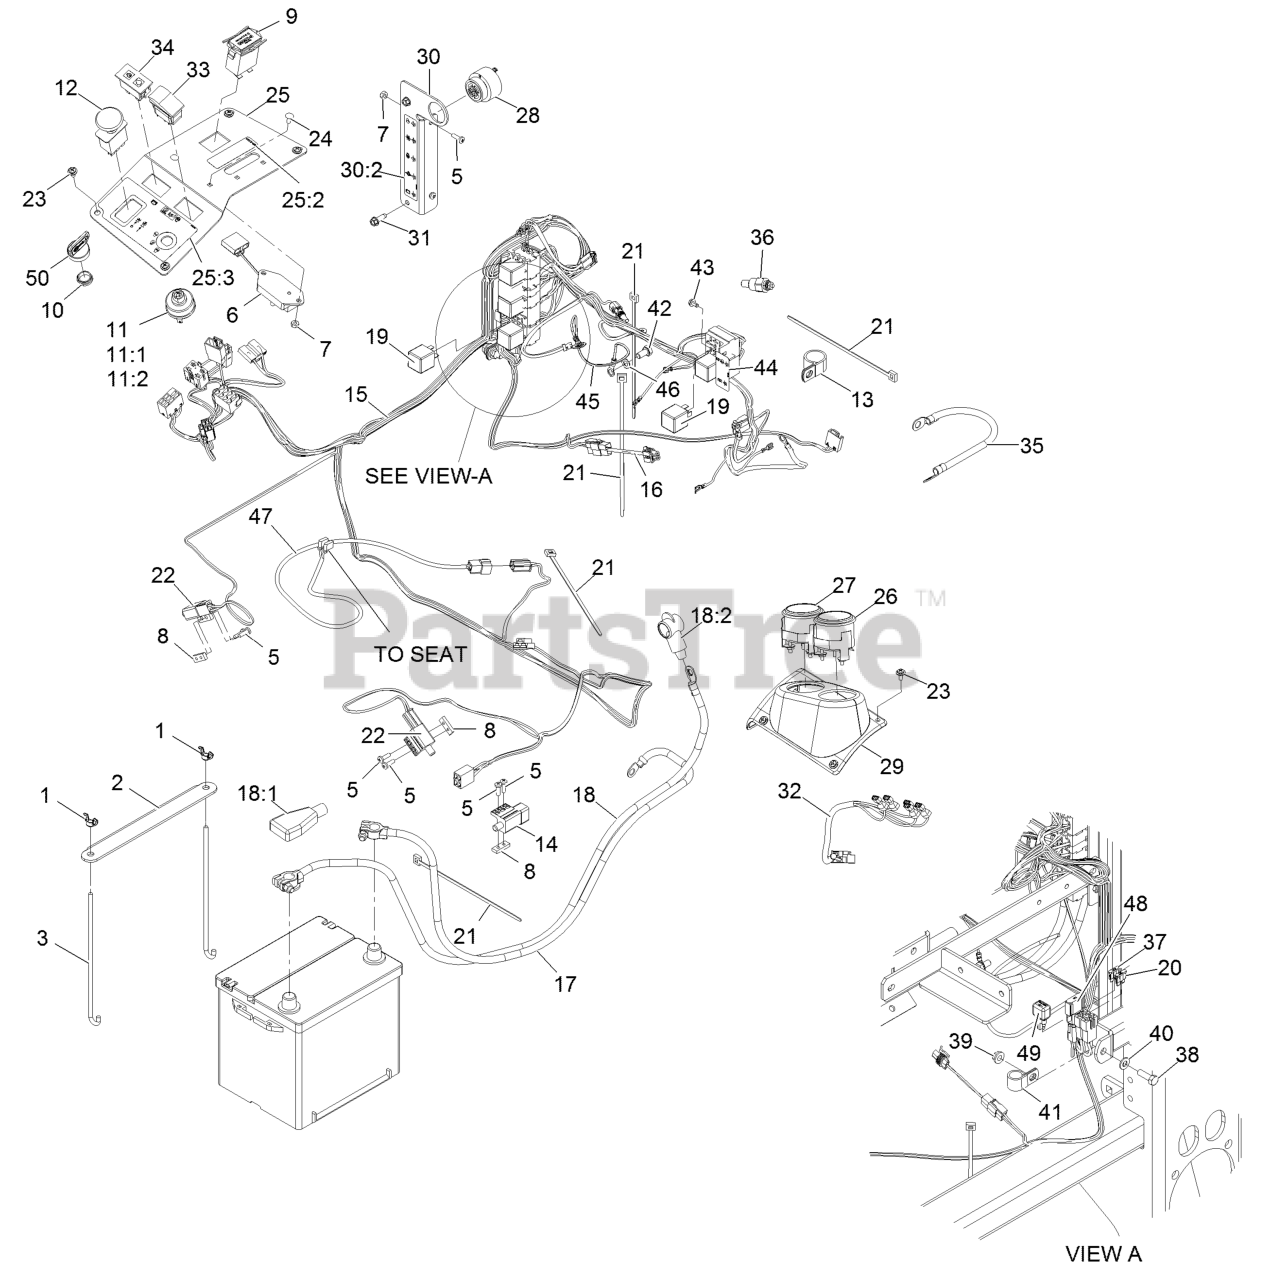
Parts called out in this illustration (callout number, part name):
1	WINGNUT
2	HOLDDOWN-BATTERY
3	BOLT-HOLDDOWN
5	SCREW-PPH
6	MODULE-DELAY, SEAT
7	NUT-LOCK, NI
8	PLATE-TAPPED
9	METER-HOUR
10	NUT-SWITCH, IGNITION
11:1	WASHER-LOCK
12	SWITCH-PTO, ON-ON
13	CLIP-LOOM
15	HARNESS,WIRING-LZDS KUBOT
16	HARNESS-WIRE
17	CABLE-BATTERY NEGATIVE
18	ASM,POSITIVE BATTERY CABL
18:1	INSULATOR-TERMINAL, BATTE
18:2	INSULATOR-STARTER
20	FUSE-BLADE TYPE, 20 AMP
21	TIE-PLASTIC
22	SWITCH-OPEN, NORMALLY
23	SCREW-PPH
24	BOLT-CARR
25	CONTROL PANEL W/DECALS
25:2	DECAL-THROTTLE
25:3	Decal-Control Panel
26	GAUGE-TEMPERATURE
27	GAUGE-VOLTMETER
28	ALARM-TONE, DUAL
29	BEZEL, GAGE XP LH TANK
30	ASM,RELAY BRKT W/ DECALS
30:2	Decal-Relay
31	SCREW-HWHTF
32	HARNESS-GAUGE
33	SWITCH-ROCKER
34	LAMP-WARNING
35	CABLE-ENGINE NEGATIVE
36	SENDER,TEMPERATURE
37	FUSE-40 AMP
38	SCREW-HH
40	WASHER-PLAIN
41	CLIP-LOOM
42	SCREW-HH
43	SCREW-HWH
44	Decal-PTO Relay
45	GROUND WIRE ASM
46	WASHER-LOCK
47	HARNESS-WIRING, SEAT
48	FUSE-BLADE, 50 AMP
50	KEY-IGNITION
